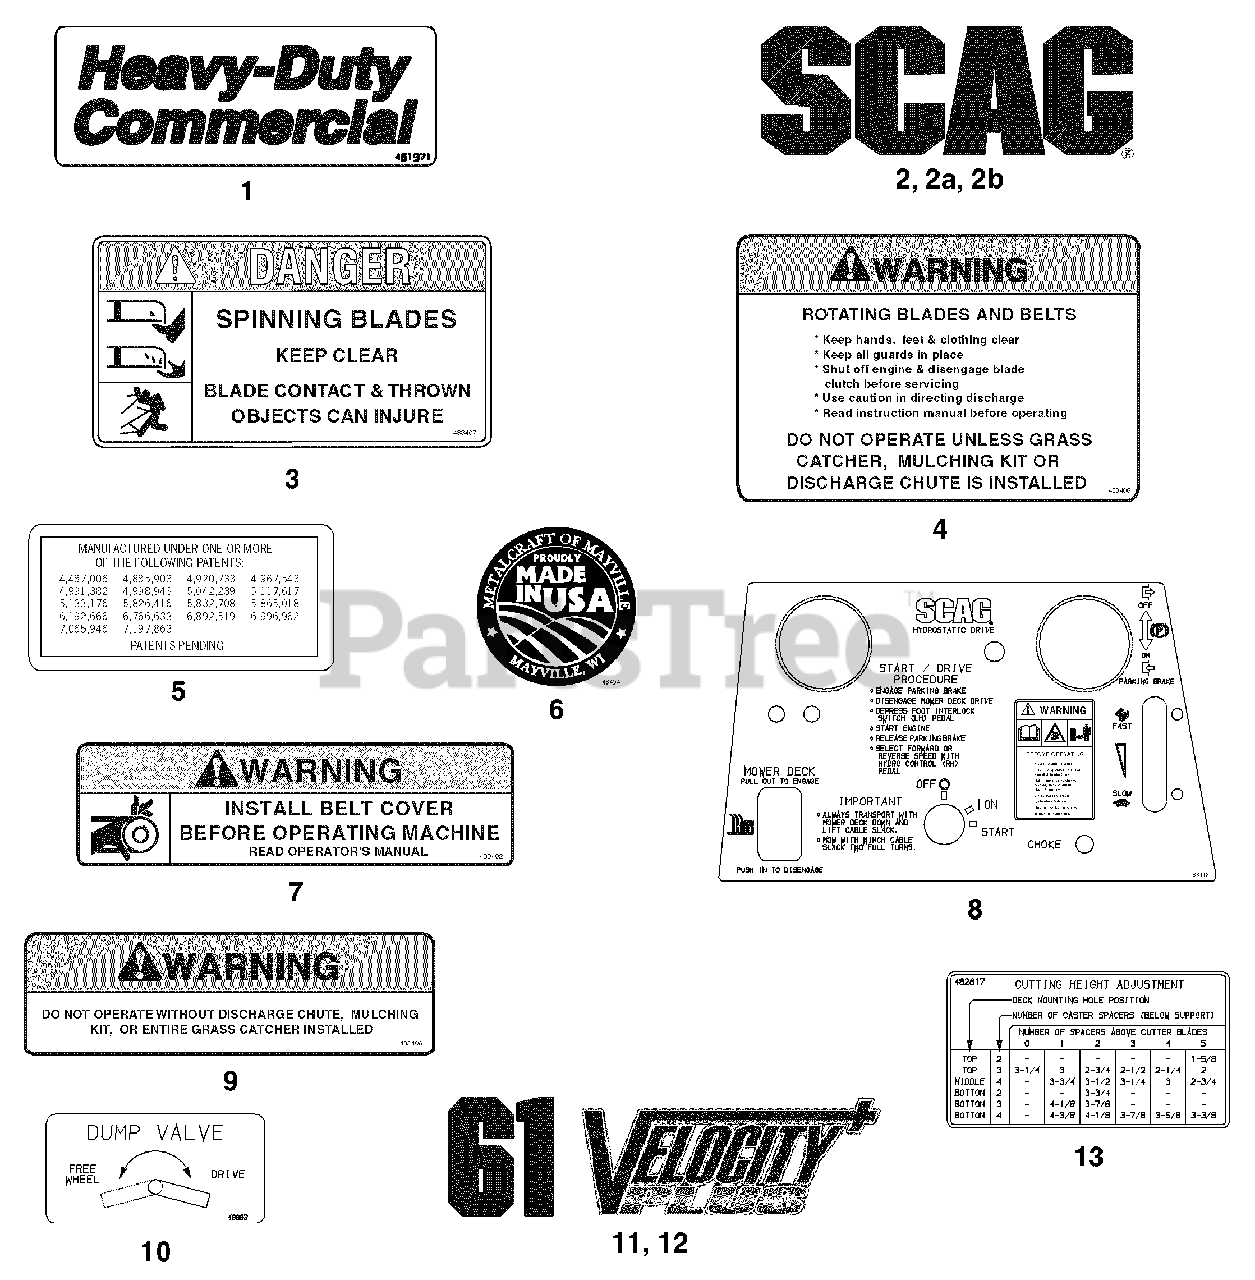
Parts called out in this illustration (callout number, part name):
1	Decal, Heavy Duty Commercial
2	Decal, Scag Logo
3	Decal, Danger-Spinning Blades
4	Decal, Warning-Rotating Blades
5	Decal, Patent
6	Decal, Metalcraft-Made In USA
7	Decal, Warning-Belt Cover
8	Decal, Instrument Panel
9	Decal, Warning-Discharge
10	Decal, Dump Valve
11	Decal, 61 Velocity Plus
12	Decal, 72 Advantage
13	Decal, Height of Cut
